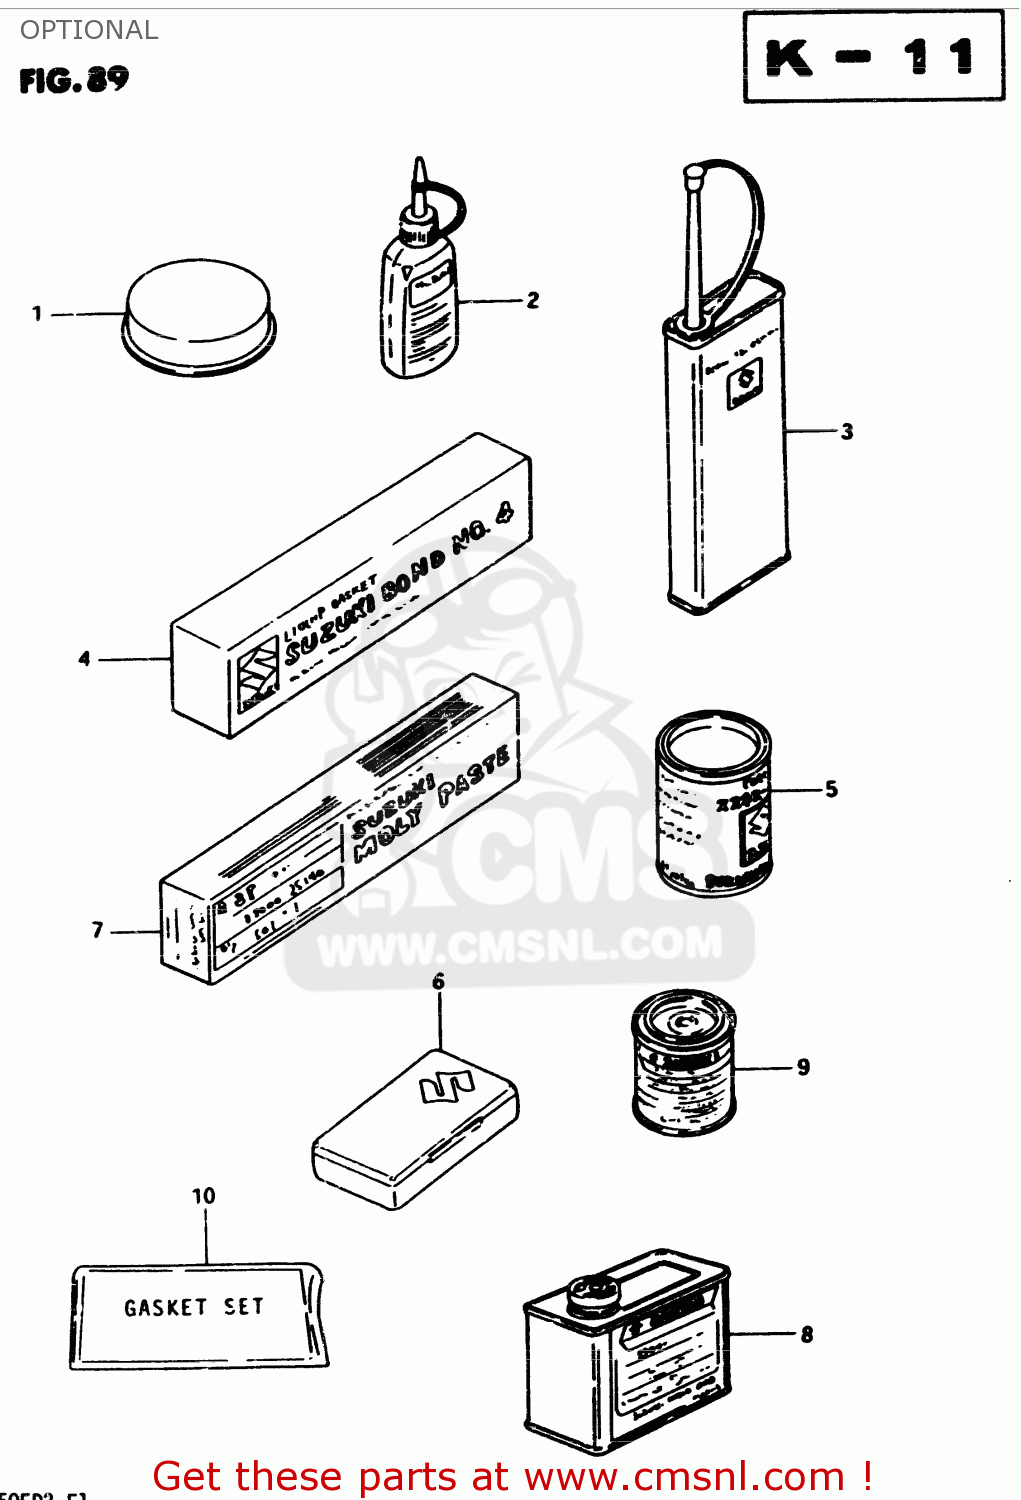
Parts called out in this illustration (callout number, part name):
1	GREASE,PBC FOR BRK PAD 20G
2	THREAD LOCK NO.1342
3	THREAD LOCK NO.1401 CLEAR 200G
4	LIQUID GSKT NO.1207B 100G BLK
5	GREASE(C)EP2 LITHIUM 150G
6	TUBE REPARING TOOL
7	SUZUKI MOLY PASTE
8	PAINT (BLACK)
9	PAINT,BLACK
10	GASKET SET
